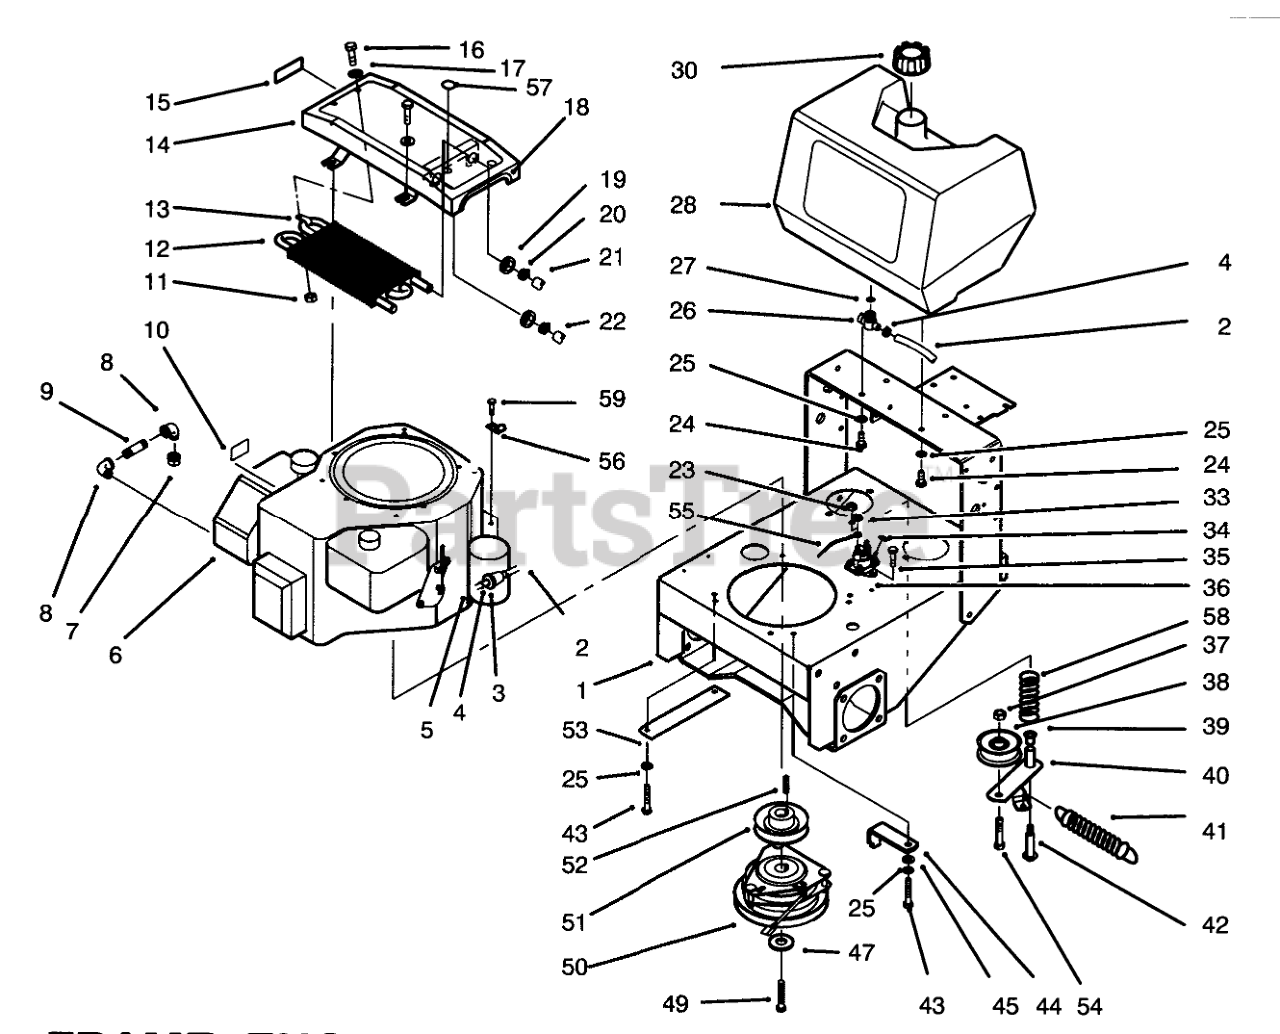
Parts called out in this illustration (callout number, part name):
1	Frame
2	HOSE-FUEL
3	FILTER-FUEL
4	CLAMP-HOSE
5	HOSE-FUEL
6	Engine-14 H.P. Kohler
7	CAP-PIPE
8	ELBOW-STREET, 90 DEG
9	NIPPLE
10	DECAL-SURFACE, HOT
11	NUT-LOCK, NI
12	Cooler-Oil
13	CLAMP-R
14	Mount-Cooler
15	DECAL-FUEL SHUT OFF
16	SCREW-HH
17	WASHER-FLAT
18	TRIM-MOUNT, COOLER
19	GROMMET
20	CLAMP-HOSE
21	HYDRAULIC HOSE ASM
22	HYDRAULIC HOSE ASM
23	NUT-LOCK
24	SCREW-HH
25	WASHER-LOCK
26	VALVE-FUEL
27	O-RING
28	FUEL TANK
30	GAS CAP ASM
33	NUT-KEPS
34	NUT-KEPS
35	SCREW-HWH
36	Solenoid
37	NUT-LOCK, NI
38	PULLEY
39	BUSHING-FLANGE
40	Idler Assembly (Incl. Ref. #39)
41	SPRING
42	BOLT-WHEEL
43	SCREW-HH
44	Retainer-Clutch
47	WASHER
49	SCREW-CLUTCH
50	CLUTCH/BRAKE
51	Pulley
52	KEY-SQUARE
53	Guard-Pulley
54	SCREW-HH
55	WIRE-SOLENOID/STARTER
56	CLAMP-R
57	PLUG-PLASTIC
58	SPRING-COMPRESSION
59	SCREW-SHWH
